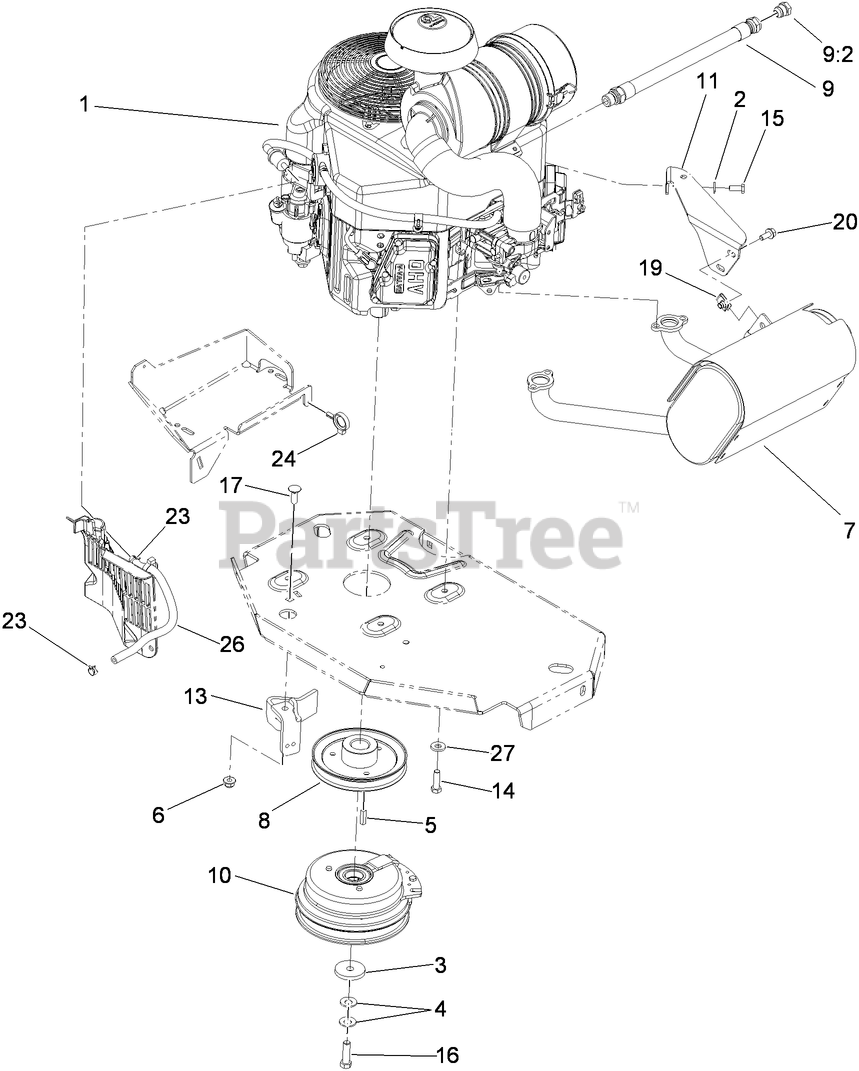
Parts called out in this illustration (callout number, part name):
2	WASHER-SPRING
3	WASHER-CLUTCH
4	WASHER-SPRING
6	NUT-HF, NI
7	MUFFLER
8	SHEAVE
9	OIL DRAIN HOSE ASM
10	CLUTCH KIT
11	BRACKET-MUFFLER
13	CLUTCH-ANCHOR
14	SCREW-HH
15	SCREW-HH
16	SCREW-HH, W/LOCTITE
17	SCREW-CARR
19	NUT-U
20	SCREW-HHF
23	CLAMP-HOSE
24	CLAMP-HOSE
26	HOSE-FUEL
27	WASHER-BELLEVILLE
